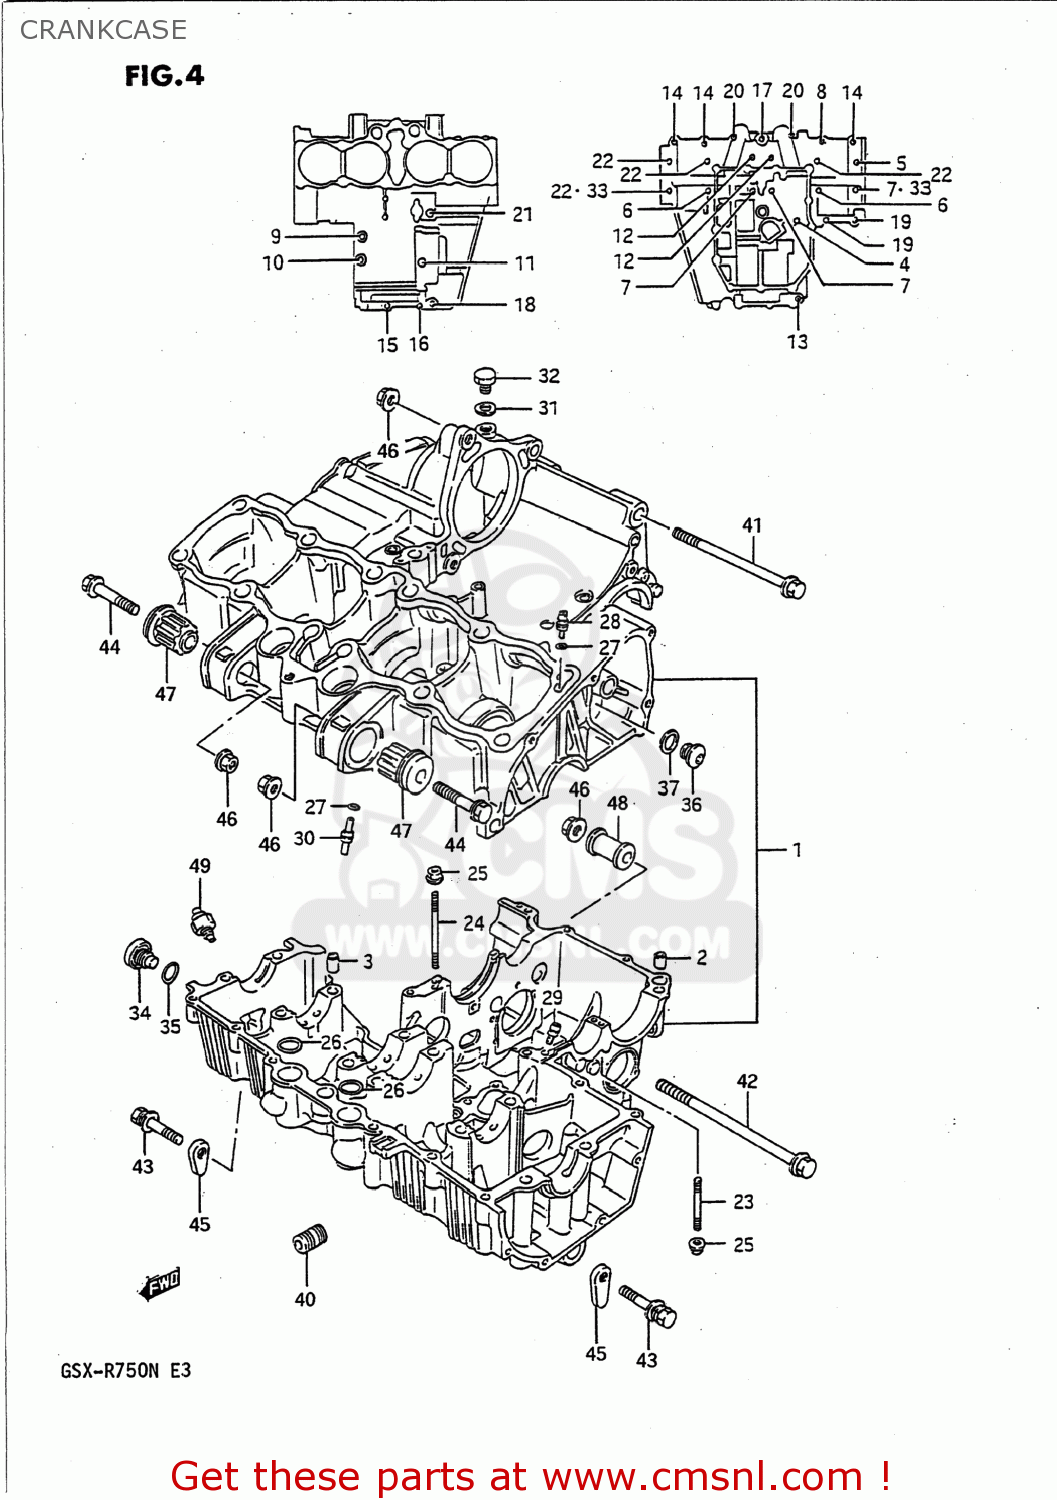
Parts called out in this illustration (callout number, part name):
1	CRANKCASE SET
2	PIN(10.4X13X22)
3	PIN (11X20)(SUS)
4	BOLT(6X105)
5	BOLT
6	BOLT(8X125)
7	BOLT 8X115
8	BOLT 6X35
9	BOLT
10	BOLT
11	BOLT
12	BOLT
13	BOLT 8X60
14	BOLT 6X35
15	BOLT
16	BOLT
17	BOLT 6X50
18	BOLT ,6X60
19	BOLT
20	BOLT
21	BOLT
22	BOLT
23	STUD BOLT
24	STUD BOLT
25	NUT
26	O RING(D:2.5,ID:21)
27	O RING(D:1.2,ID:4)
28	JET,AIR
29	JET
30	JET,OIL GALLERY
31	GASKET(12.1X16.2X3.7) (NAS)
32	PLUG(12X9)
33	GASKET(8.5X17X2.3) (NAS)
34	PLUG
35	O RING(D:2.4,ID:16.8)
36	PLUG,14X12
37	GASKET(14X19.2X2) (NAS)
38	PLATE,CRANK THRUST
39	PLATE,CRANK THRUST
40	UNION,OIL STAND
41	BOLT 10X150
42	BOLT(10X175)
43	BOLT
44	BOLT 10X55
45	NUT
46	NUT
47	BUSH,ENGINE MOUNTING
48	SPACER,ENGINE MOUNT
49	SWITCH ASSEMBLY
